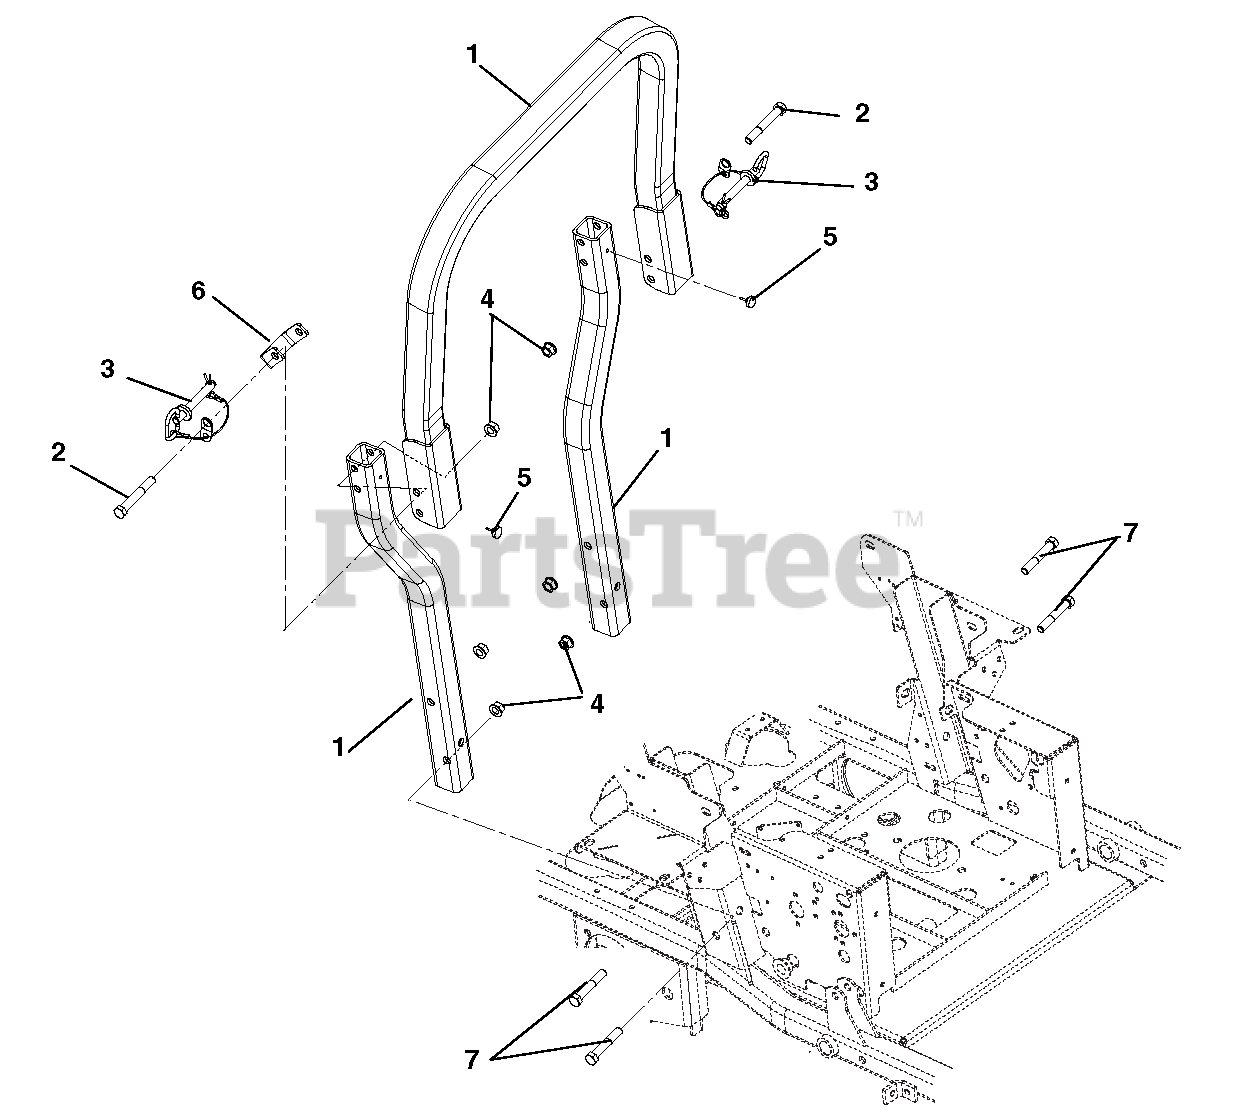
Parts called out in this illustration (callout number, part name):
1	ROPS, PM200 REPLACEMENT
2	@BLT-HEX .50-13X3.50 GR5 YWZC
3	ASSY, ROPS PIN/LANYARD
4	@NUT-LK-TOP-FLG .50-13 YWZC
5	BUMPER, ROPS RUBBER
6	BRKT, ROPS STOP,PRO-MASTER BLK
7	@BLT-HEX .50-13X3.00 GR5 YWZC
